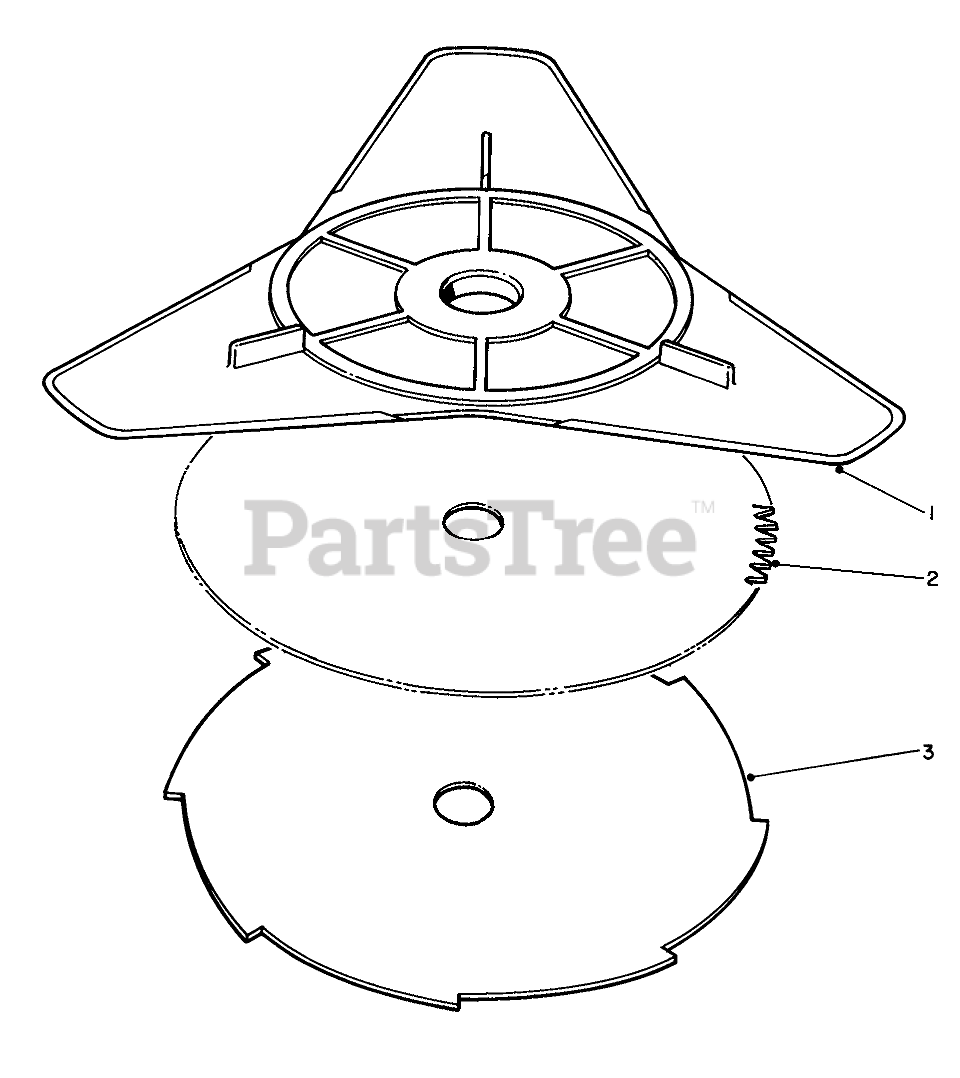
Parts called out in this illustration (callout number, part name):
1	FLEX BLADE PKG
2	8" Blade (80)
3	8" Blade (8T)
